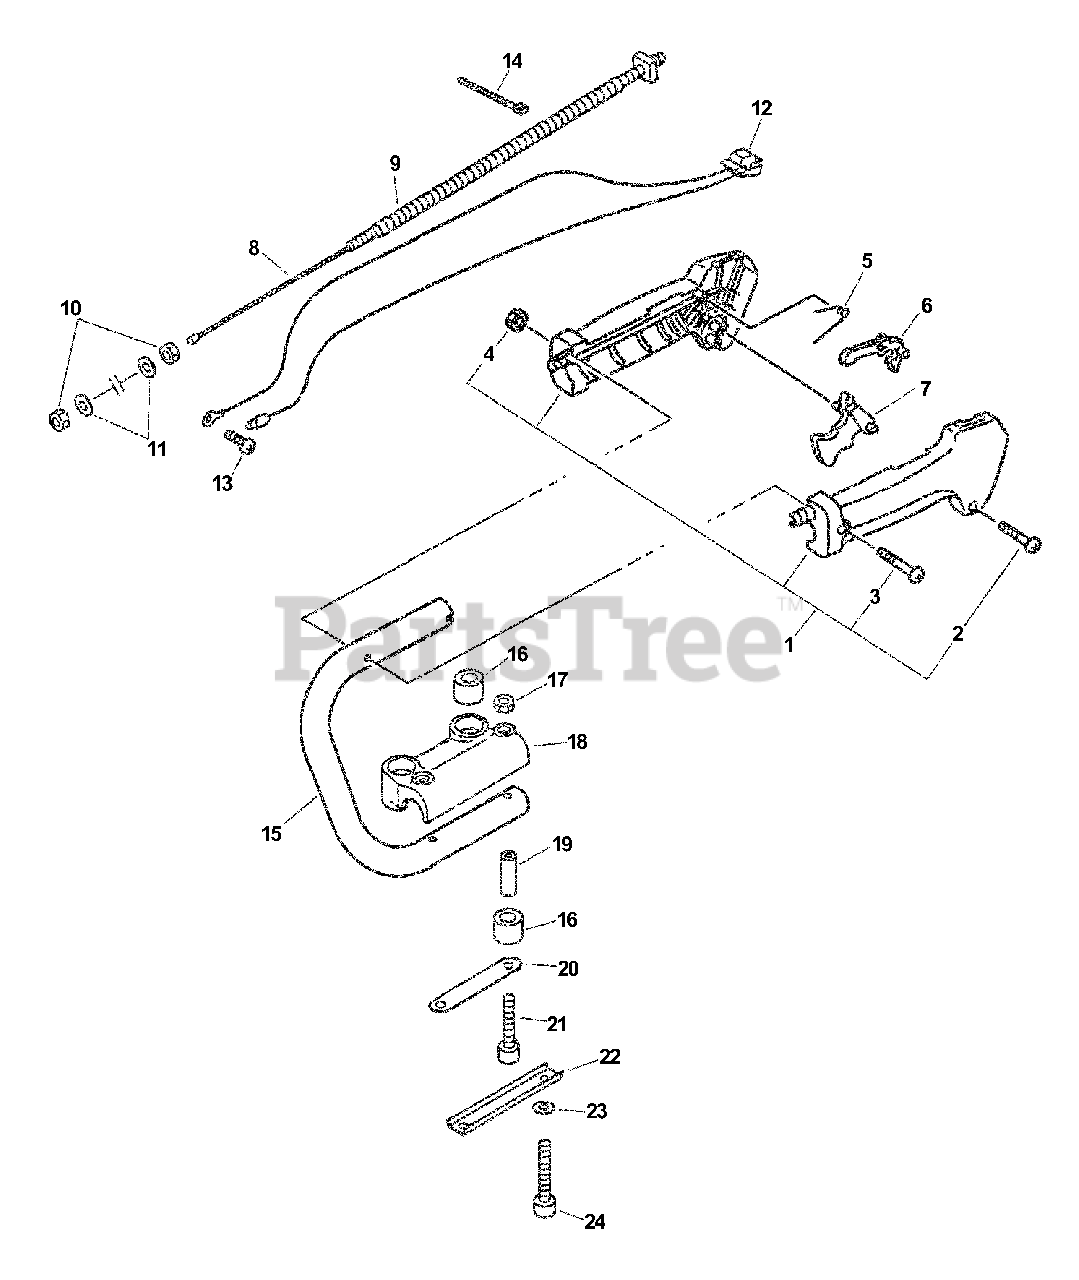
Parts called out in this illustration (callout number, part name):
1	CONTROL HANDLE KIT
2	SCREW 3×25
3	SCREW 5×30
4	NUT M5
5	SPRING, TORSION
6	LOCKOUT, THROTTLE
7	TRIGGER, THROTTLE
8	CABLE, THROTTLE
11	WASHER 6.5×11.5×0.8
12	IGNITION SWITCH ASSY
13	SCREW 5×10
14	TIE, CABLE
15	HANDLE, REAR
17	NUT M5
18	SUPPORTER, HANDLE
19	SPACER
20	PLATE, EYE
21	BOLT 5×45
23	WASHER 5.5×18×1
24	BOLT M5×35
